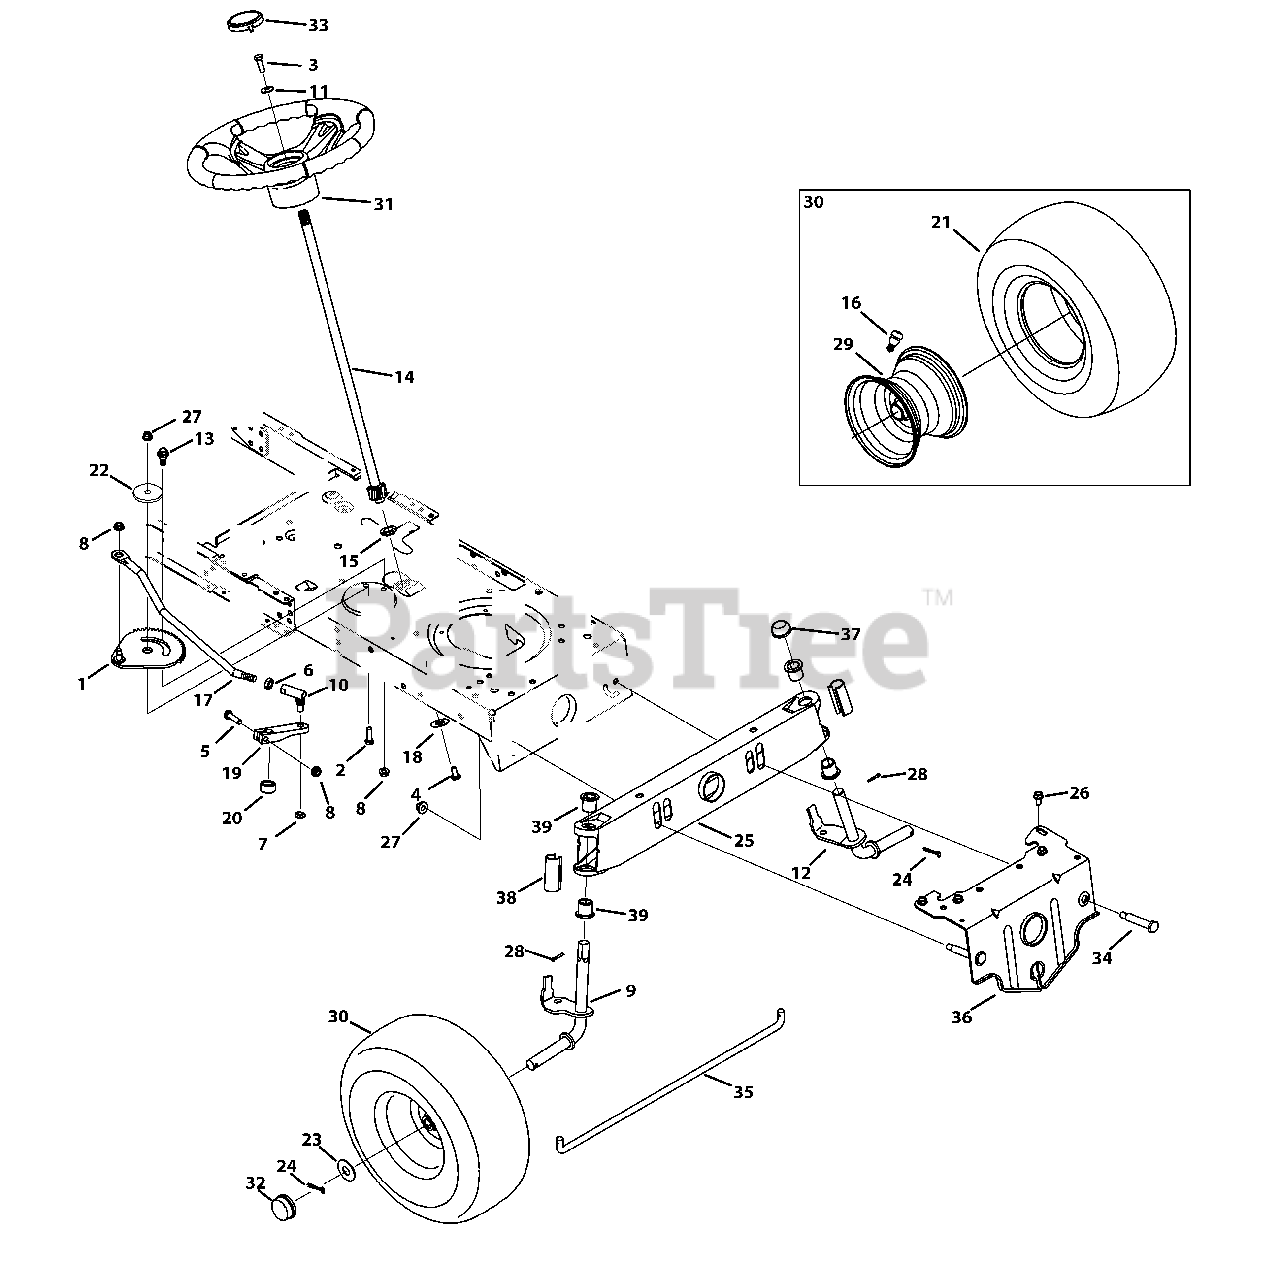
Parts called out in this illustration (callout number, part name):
1	Front Steering Gear Assembly
2	Hex Screw, 3/8-16 x 1.00
3	Hex Screw, 5/16-18 x 1.00, Lock
4	Machine Screw, 5/16-18 x .750
5	Hex Screw, 5/16-18 x 1.75
6	Jam Nut, 7/16-20
7	Jamlock Nut, 3/8-24
8	Flangelock Nut, 5/16-18
9	Front RH Axle
10	Ball Joint, 7/16-20
11	Bell Washer, .340 x .872 x .060
13	Shoulder Bolt, 5/16-18 x .435 x .350
14	Steering Shaft, 5/8 x 22.08
15	Flange Bearing, 5/8
16	Valve, tubeless Air
17	Steering Link
18	Cap, 1.25 x .16
19	Steering Block
20	Spacer, .71 x .125 x .56
21	Tire, 15 X 6 X 6 Sq Shoulder
22	Shoulder Spacer, .884 x .190
23	Flat Washer, .781 x 1.590
24	Cotter Pin, 5/32 x 1.25
26	Screw, 5/16-18 x .750
27	Flangelock Nut, 3/8-16
28	Cotter Pin, .125 x .75
29	Rim Assembly, 6.0x4.5
30	Wheel Assembly
31	Steering Wheel
33	Cap, Troy-Bilt
34	Shoulder Bolt, 3/8-16 x .500 x 2.38
36	Pivot Bar Bracket
37	Push Cap, 3/4
38	Standard Axle Cap
39	Flange Bearing, .760 x .941 x 1.0
